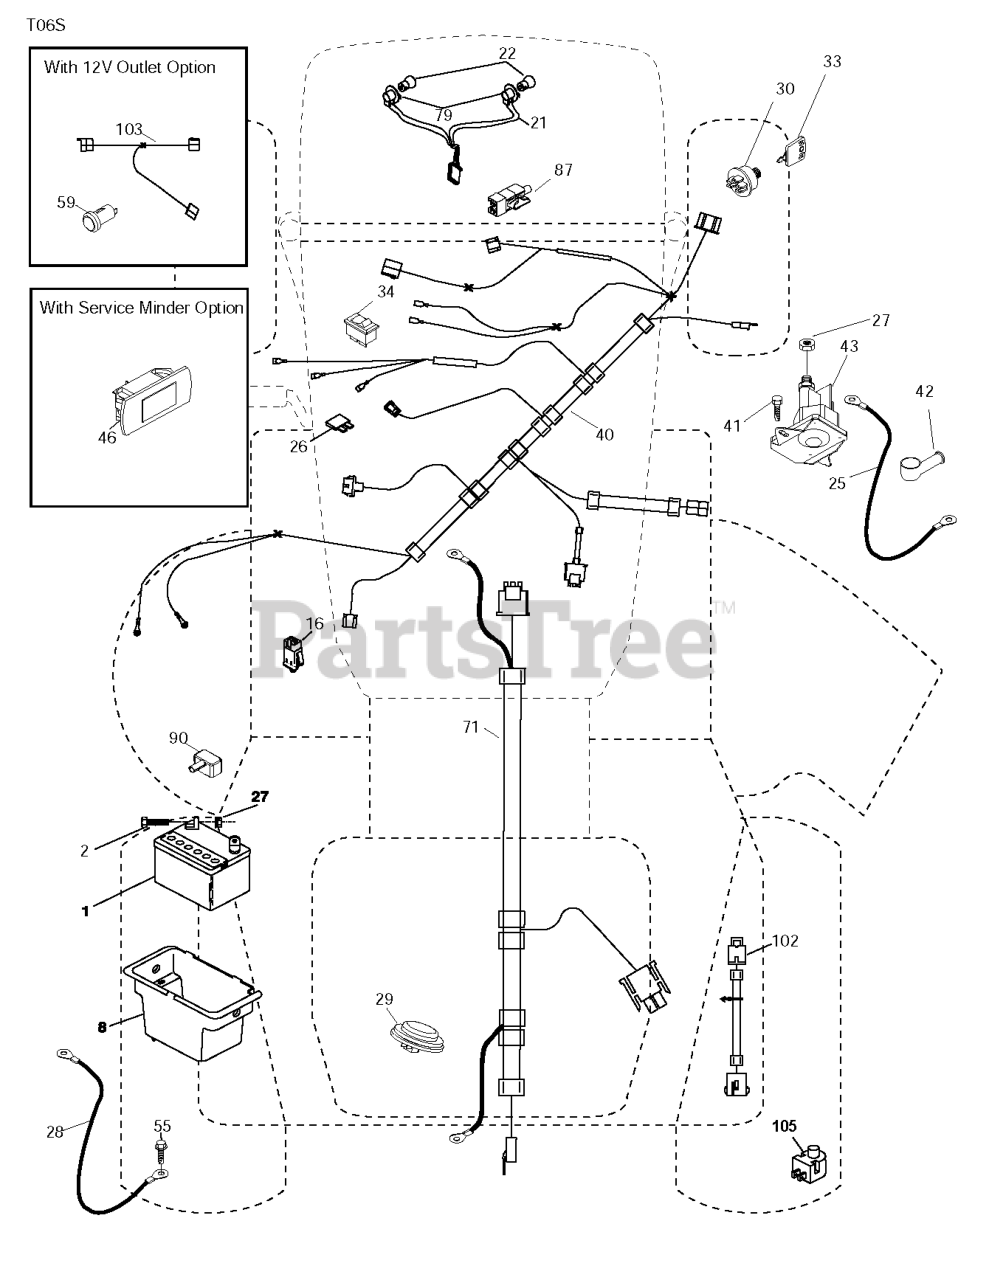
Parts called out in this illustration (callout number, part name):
1	Battery 12 Volt 25 Amp
2	BOLT.HEX.1/4.X.3/4.DICHROMATE
8	BOX.BATTERY.MNT.REAR.L
16	SWITCH INTERLOOK PUSH-IN
21	HARNESS.LIGHT W/4152J BULBS
25	CABLE.STARTER.6GA.BL/RED.14.
26	FUSE 20AMP
27	NUT
28	CABLE.BLACK.18"REAR.BA
29	SWITCH.SEAT.DELTA.OPC.
30	SWITCH.IGN.DELTA.W.LGH.ROS
33	KEY.CHAIN.BLISTER.PACK.GEN.USA
40	HARNESS IGN. DASH
41	SCREW
42	TERMINAL COVER
43	SOLENOID.W/BRASS.PLUNGER
46	RP.GUAGE.SRVCMNDR.HRMTR.
55	SCREW 5/16"
71	HARNESS.IGN.CHASS.TEX.REAR.BAT
79	BULB HOLDER ASM.
87	SWITCH.INTRLCK.CLUTCH.
90	COVER, TERMINAL BATTERY
102	HARNESS PIGTAIL PCH TEX ROS
105	REVERSE SWITCH
